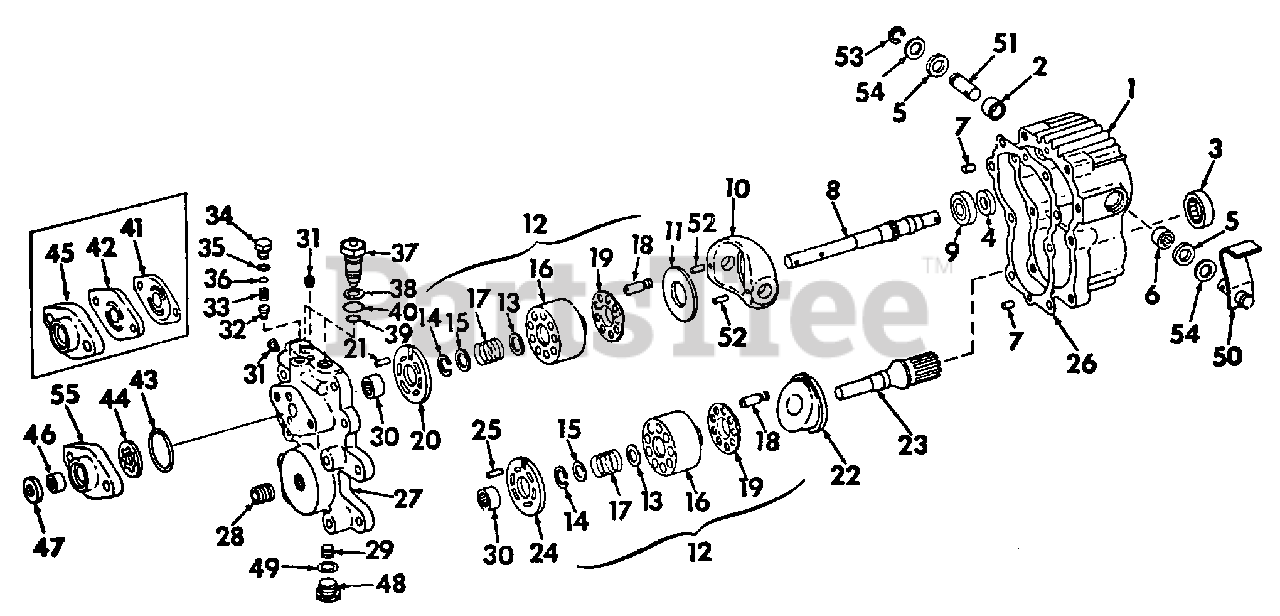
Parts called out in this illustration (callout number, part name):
1	Housing Assy
2	Not used in this application
3	Bearing, Hyd Pump Shaft Roller
4	Seal, Lip
5	Seal, Lip
6	Bearing, Needle
7	Pin, Transmission Housing
8	Shaft, Transmission Hyd Pump
9	Bearing, Ball
10	Swashplate, Hyd Pump
11	Plate, Hyd Pump Swashplate Thrust
12	Kit, Cylinder Block Motor & Pump
13	Washer, Spring Front
14	Ring, Hyd Cylinder Block Spring Rear Washer Snap
15	Washer, Hyd Cylinder Block Spring Rear
16	Block, Cylinder
17	Spring, Hyd Cylinder Block
18	Piston Assy, Hyd Pump & Motor
19	Retainer, Hyd Piston Slipper
20	Plate, Hyd Cylinder Block Valve
21	Pin, Hyd Pump Cylinder Block
22	Swashplate, Hyd Motor
23	Shaft, Transmission Hyd Motor
24	Plate, Hyd Motor Cylinder Block Valve
25	Pin, Hyd Motor Cylinder Block
26	Gasket, Transmission Housing
27	Housing, Center Section
28	Fitting, Center Housing Oil Filter
29	Plug, 1/4-18 Automotive Hex Soc Hd Pipe
30	Bearing, Center Housing Needle
31	Plug, 1/8-27 Automotive Hex Soc Hd Pipe
32	Cone, Charge Pump Relief Valve
33	Spring, Charge Pump Relief Valve
34	Plug, Charge Pump Relief Valve
35	O-Ring, 13/32 x 9/16 x 5/64 Relief Valve Plug
37	Valve Assy, Center Housing Check
38	Washer, Check Valve Housing Back Up
39	O-Ring, 5/8 x 3/4 x 1/16 Check Valve Housing Small
40	O-Ring, 3/4 x 15/16 x 3/32 Check Valve Housing Large
41	Gasket, Charge Pump Port Plate
42	Plate, Charge Pump Port
43	O-Ring, 2-1/8 x 2-3/8 x 1/8
43	O-Ring, 2-3/8 x 2-1/2 x 16 Class 5
44	Rotor Assy, Charge Pump
45	Housing Assy, Charge Pump
45	Housing, Charge Pump
46	Bearing, Charge Pump Housing Needle
47	Seal, Lip
48	Plug, 3/4-16 C-Z Str Thrd O-Ring Boss Center Hsg
49	O-Ring, 41/64 x 13/16 x 3/32 Center Hsg O-Ring Plug
50	Shaft Assy, Trunnion
51	Shaft, Trunnion
52	Pin, 3/16 x 5/8 Slt Spring
53	Ring, Trunnion Shaft Snap
54	Washer, Trunnion Shaft Seal Retaining
55	Housing, Charge Pump
